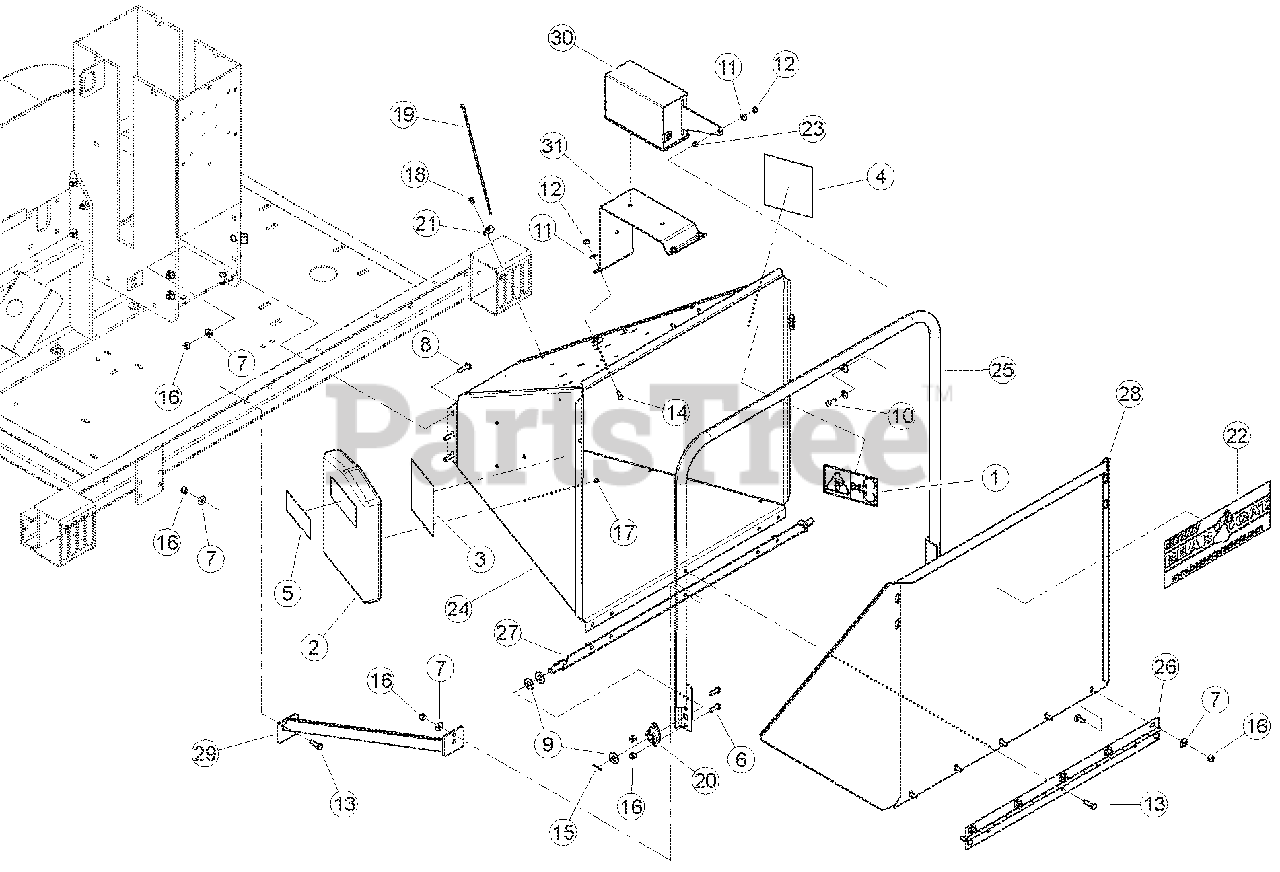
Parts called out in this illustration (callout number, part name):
1	RIVET, 1/4 X 3/4 ST POP
2	DECAL, BLADE DANGER ISO
3	DECAL, MAINTENANCE ISO
4	CONTAINER, INSTRUCTION MANUAL
5	DECAL, FEED POSITION
6	DECAL, FEED POSITION
7	DECAL, MUTILINGUAL MANUAL
8	BOLT, 3/8 X 1 HEX HD GR5 ZP
9	WASHER, 3/8 FLAT ZP
10	BOLT, 3/8 X 1-1/2 CRG GR5 ZP
11	WASHER, 5/8 SAE FLAT ZP
12	BOLT, 5/16 X 1 HHCS GR5 NC ZP
13	WASHER, 5/16 FLAT ZP
14	NUT, 5/16 NE NYLOCK ZP
15	BOLT, 3/8 X 1-1/4 HEX HD GR5 ZP
16	BOLT, 5/16 X 3/4 CRG GR5 NC ZP
17	PIN, 1/8 X 1.00 ZP COTTER
18	NUT, 3/8 NE NYLOCK ZP
19	RIVET, 1/4 X 1/2 DOME HD BLIND SS
20	STRAP, 11 IN. BLACK TIE
21	BEARING, SIDE FLNG MOUNT 5/8"
22	CLAMP, CABLE MOUNT
23	SPACER, IDLER PIVOT
25	WELDMENT, CONTROL ARM
26	HINGE, EXTENSION TRAY
27	WELDMENT, CONTROL PIVOT
29	WELDMENT, CHUTE SUPPORT
30	ASSEMBLY, SWITCH BOX
31	MOUNT, SWITCH BOX
